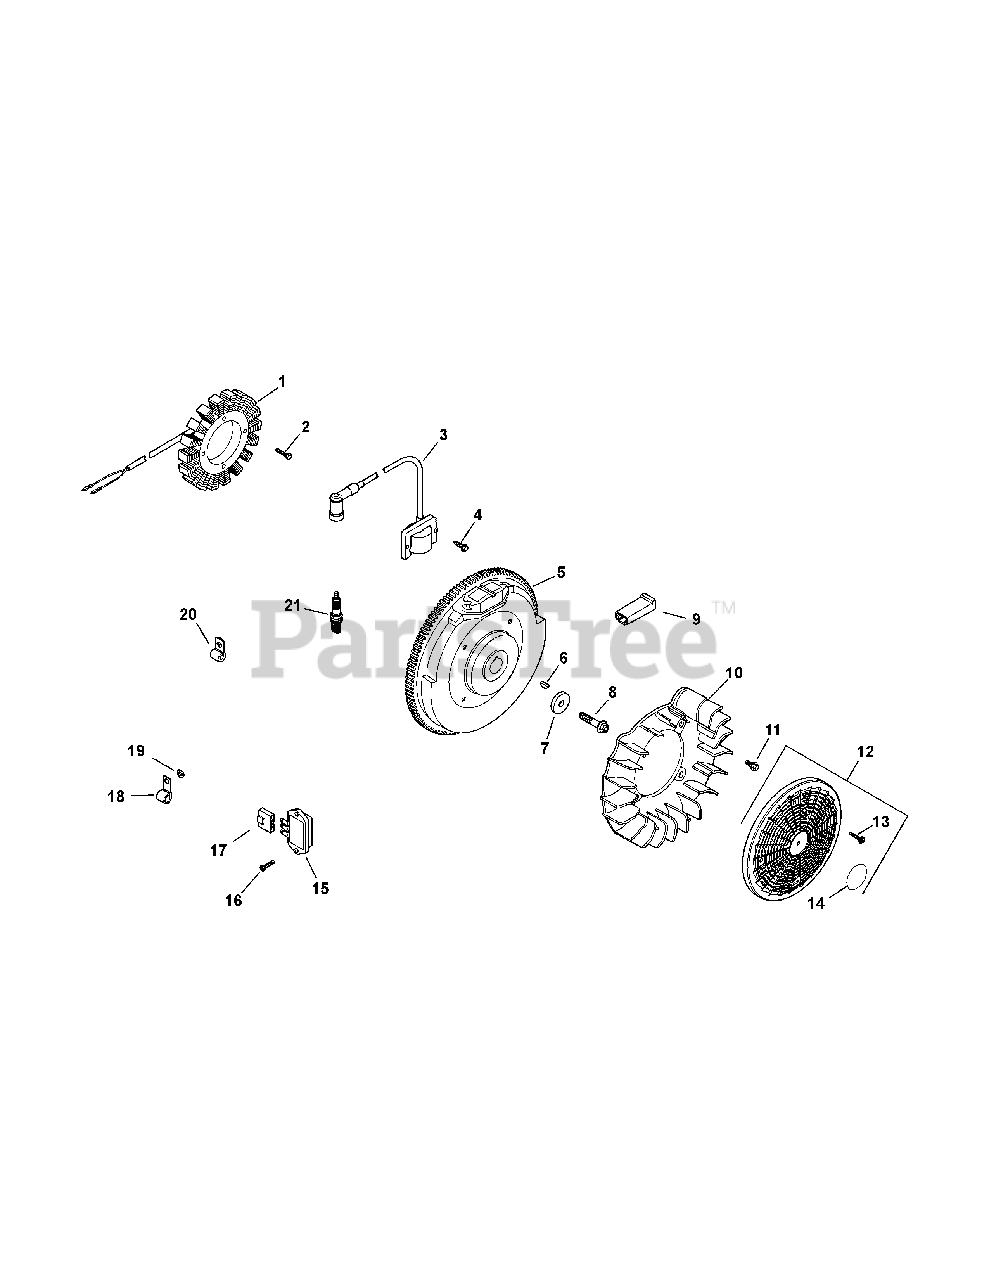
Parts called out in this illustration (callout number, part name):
1	KIT, 15 / 20 AMP STATOR
2	SCREW, THD FRM M5X0.8X25
3	KIT, MODULE IGNTN (CDI FIXED)
4	SCREW, FLG THD FRM M5X.8X20
5	FLYWHEEL ASSEMBLY
6	KEY, 3/16'' X 5/8''4
7	WASHER, FLAT 13/32''
8	SCREW, FLG M10X1.5X45
9	CONNECTOR (1 CONTACT)
11	BOLT, SHOULDER
12	KIT, GRASS SCREEN
13	SCREW, FLG SEMS M4X.7X25
14	DECAL, GRASS SCREEN
15	REGULATOR/RECTIFIER
16	SCREW, HEX FLANGE HI-LO
17	CONNECTOR USE 25 155 41-S
18	CLIP, CABLE
19	WASHER, FLAT 1/4'' (O.D. 1/2'')
21	PLUG, SPARK (STD)
